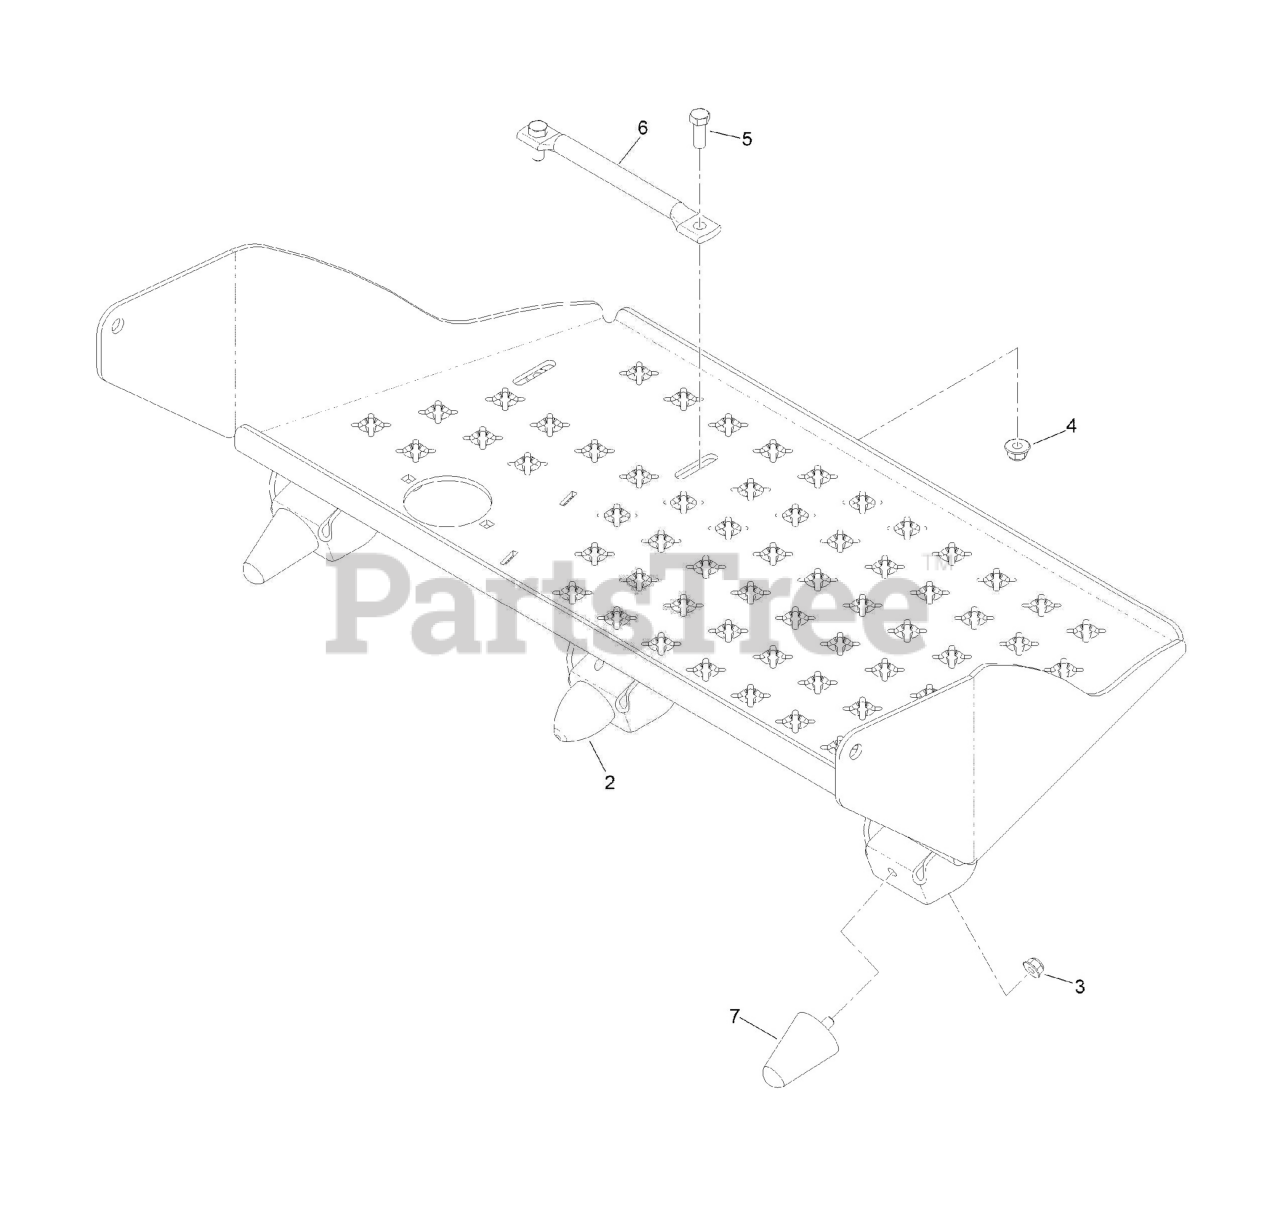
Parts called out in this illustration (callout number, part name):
2	BUMPER-RUBBER
3	NUT-HF, NI
4	NUT-HF, NI
5	SCREW-HH
6	ROCKER-PEDAL, FOOT
7	BUMPER-RUBBER
